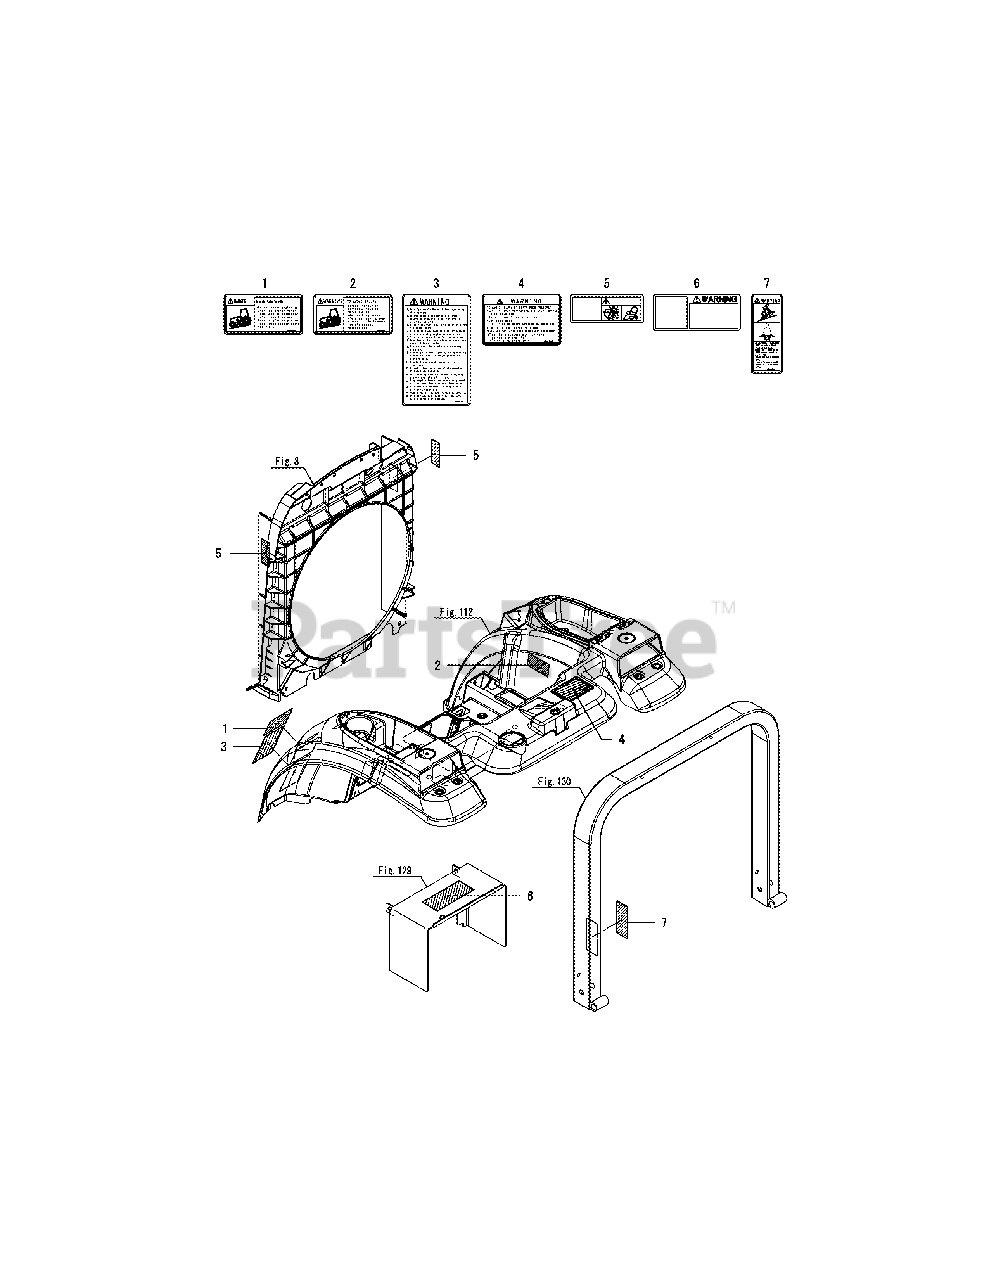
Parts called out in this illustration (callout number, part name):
1	LABEL, DANGER, START
2	LABEL, WARNING, STOP
3	LABEL, WARNING
4	LABEL, WARNING, ROPS
5	LABEL,WARNING,FAN
6	LABEL, P.T.O. WARNING
7	LABEL, WARNING ROPS
